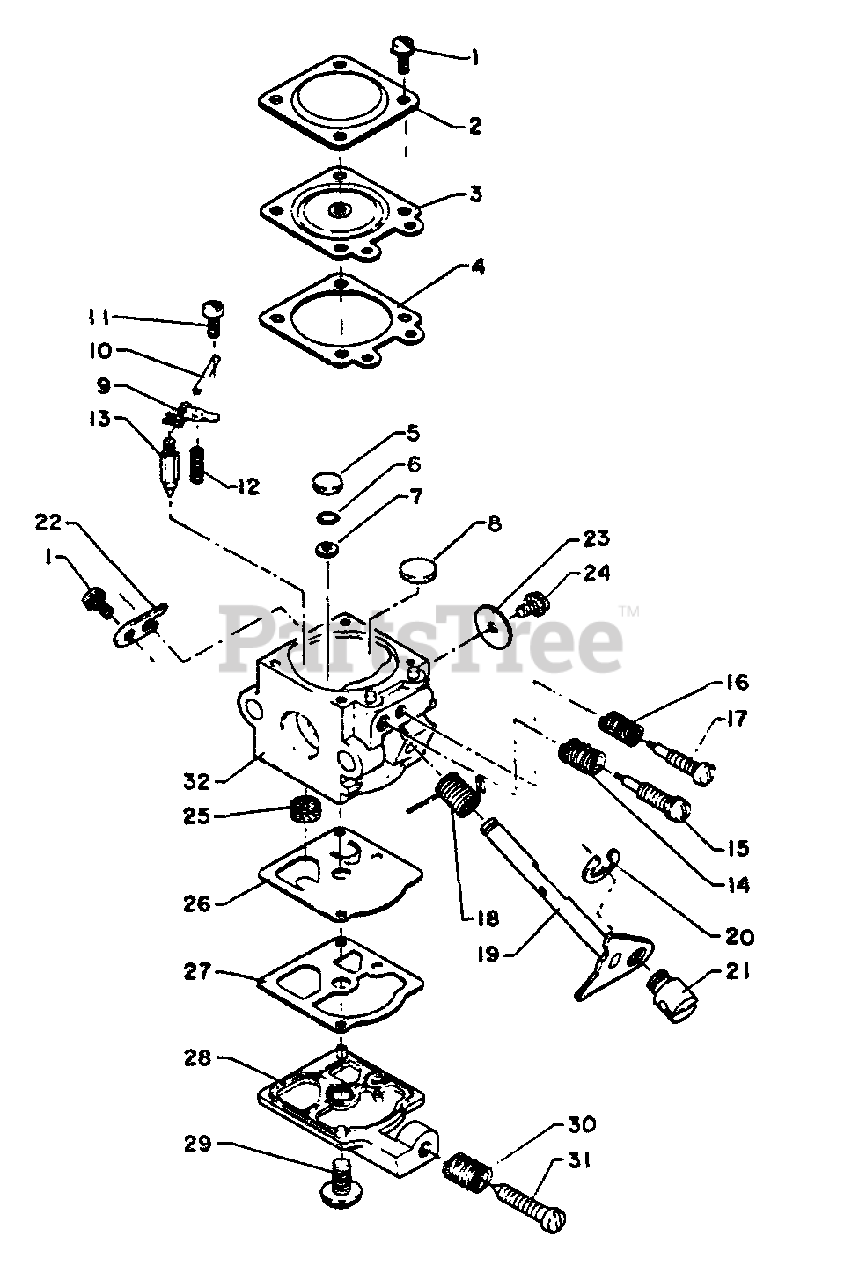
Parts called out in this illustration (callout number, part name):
2	COVER, METERING
3	DIAPHRAGM, METERING
4	GASKET, METERING
5	PLUG, WELCH
6	RING, RETAINING
7	SCREEN, SPARK ARRESTOR
8	PLUG, WELCH
9	LEVER, METERING
10	PIN, METERING LEVER
11	SCREW, METERING LEVER PIN
12	SPRING, METERING LEVER
13	VALVE, INLET NEEDLE
15	NEEDLE - HIGH SPEED
16	SPRING, IDLE ADJUST
17	NEEDLE - LOW SPEED
18	SPRING, THROTTLE RETURN
19	SHAFT, THROTTLE
20	RING, RETAINING
22	CLIP, THROTTLE SHAFT
23	VALVE, THROTTLE
25	STRAINER
26	DIAPHRAGM, PUMP
27	GASKET, PUMP
28	COVER, PUMP
29	SCREW, PUMP COVER
30	SPRING, IDLE ADJUST
31	SCREW, IDLE ADJUST
32	LABEL - GENERATOR
